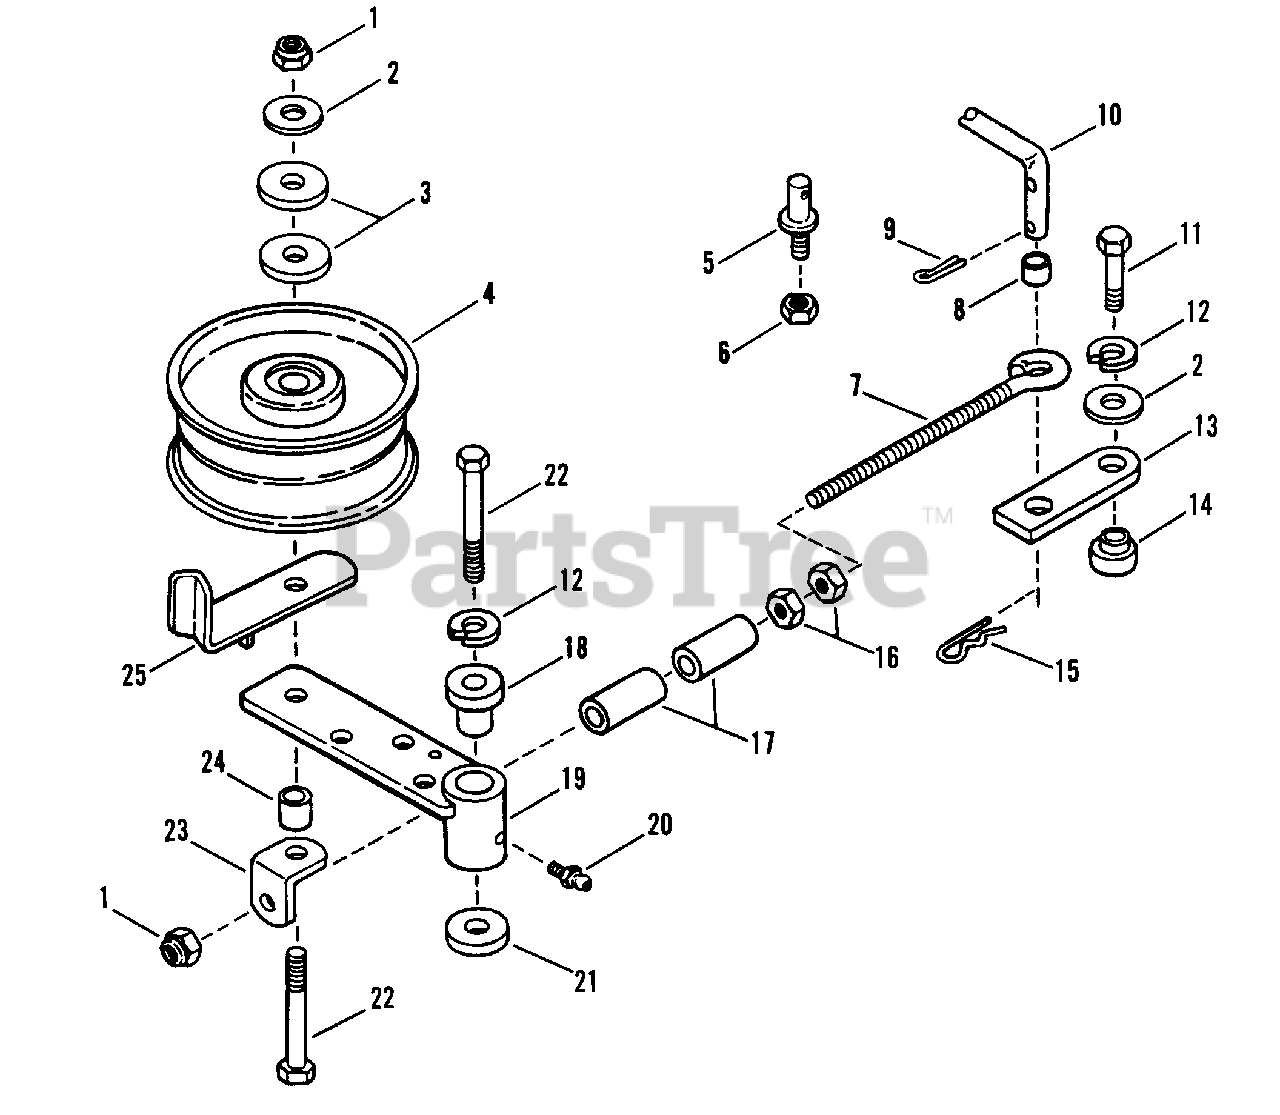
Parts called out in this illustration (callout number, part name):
1	NUT, 3/8-16 HEX NYLON LOCK
2	WASHER, 3/8" USS
3	WASHER
4	PULLEY, 5" Idler
5	STUD
6	NUT, 3/8-24 Hex Lock
7	LINK STUD, Blade Engagement
8	SLEEVE, Linkage
9	COTTER-PIN, 3/32 x 1"
10	LINK, Blade Engagement
11	SCREW, 3/8-16 x 1 1/2" Hex Cap Gr. 5
12	WASHER, 3/8 Split Lock
13	LINK, Blade Assist
14	SPACER, Pivot
15	PIN, Hair, 3/32 x 1 3/16"
16	NUT, 3/8-16 Hex
17	BUSHING
18	SPACER, Pivot
19	IDLER ARM, Weldment
20	FITTING, Lube
22	BOLT, 3/8-16 x 3" Hex Cap, Gr. 5
23	ANGLE, Blade Engagement
24	SPACER, Blade Linkage
25	GUIDE, Belt
